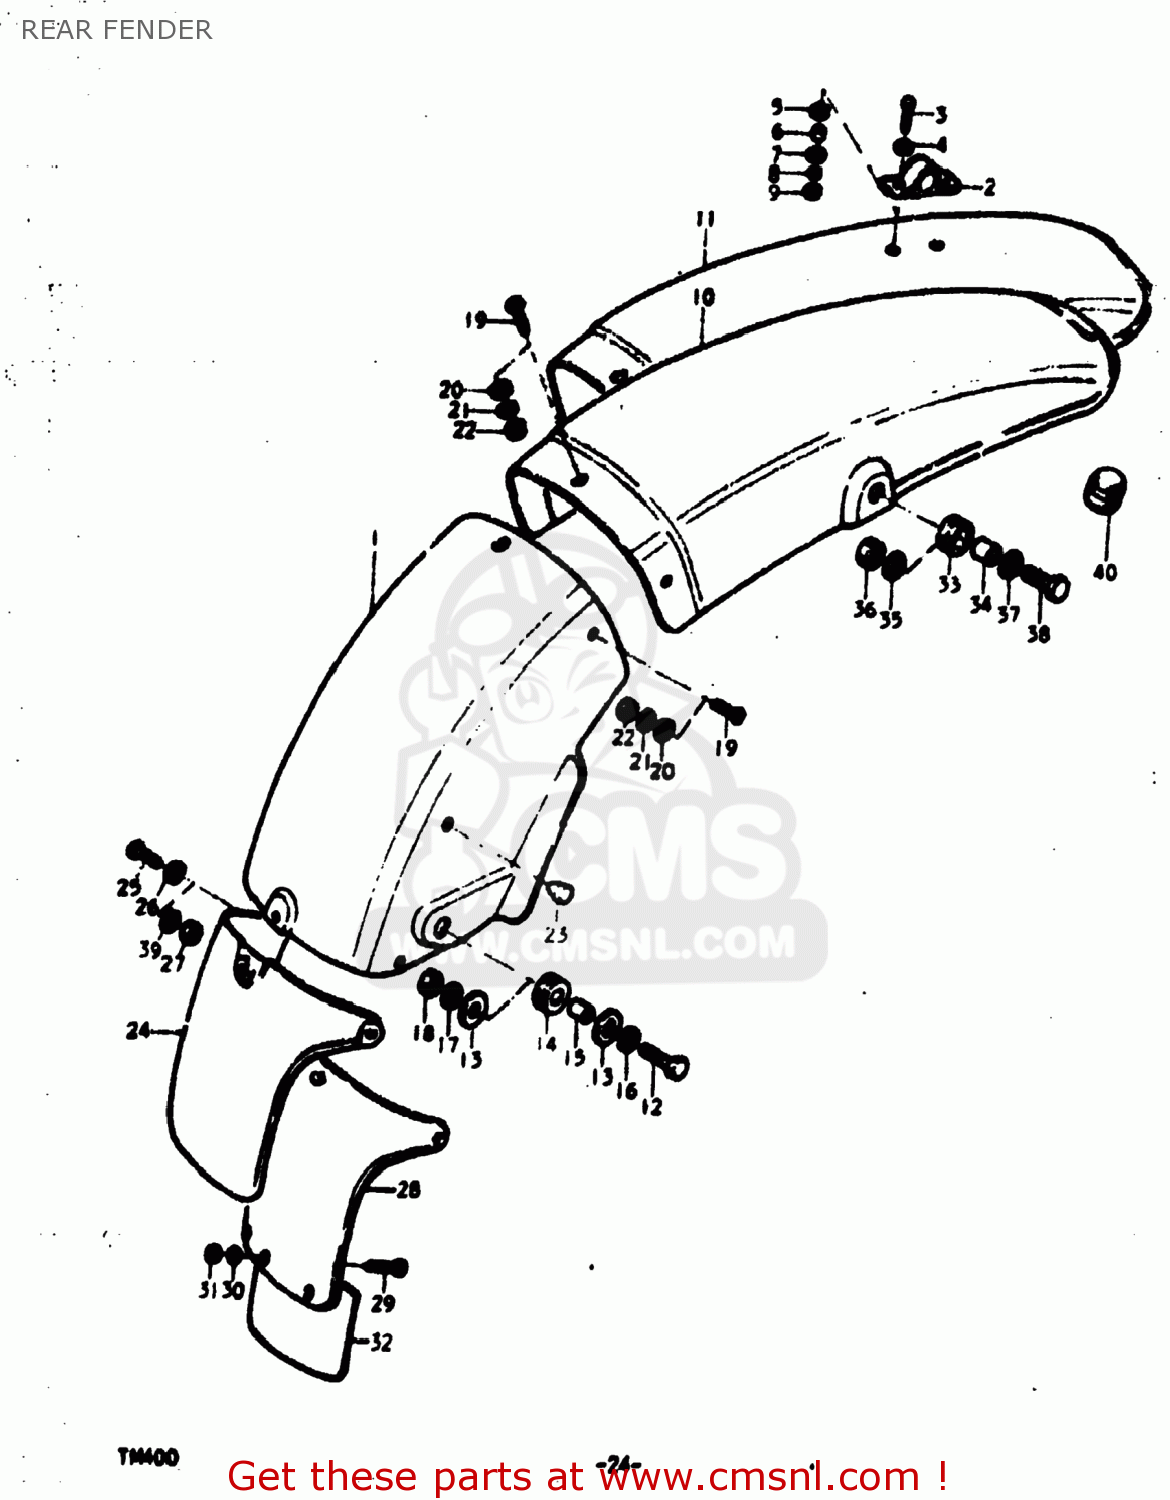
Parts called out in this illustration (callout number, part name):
1	FENDER,REAR
2	REINFORCEMENT,REAR FENDER
3	BOLT(6X18)
4	WASHER
5	CUSHION
6	SPACER
7	WASHER (6.5X20X1.2)
8	LOCK WASHER
9	NUT
10	FENDER,REAR
11	FENDER,REAR
12	BOLT
13	WASHER (6.5X20X1.2)
14	CUSHION
15	SPACER(6.1X9X7.5)
16	WASHER
17	LOCK WASHER
18	NUT
19	SCREW
20	WASHER
21	LOCK WASHER
22	NUT
23	CUSHION
24	MUD GUARD,REAR FENDER
25	SCREW
26	WASHER
27	NUT
28	MUD GUARD,REAR FENDER
29	SCREW
30	WASHER
31	NUT
32	GUIDE,RR FENDER MUD
33	CUSHION
34	SPACER(6.1X9X7.5)
35	LOCK WASHER
36	NUT
37	WASHER (6.5X20X1.2)
38	BOLT
39	LOCK WASHER
40	CUSHION
